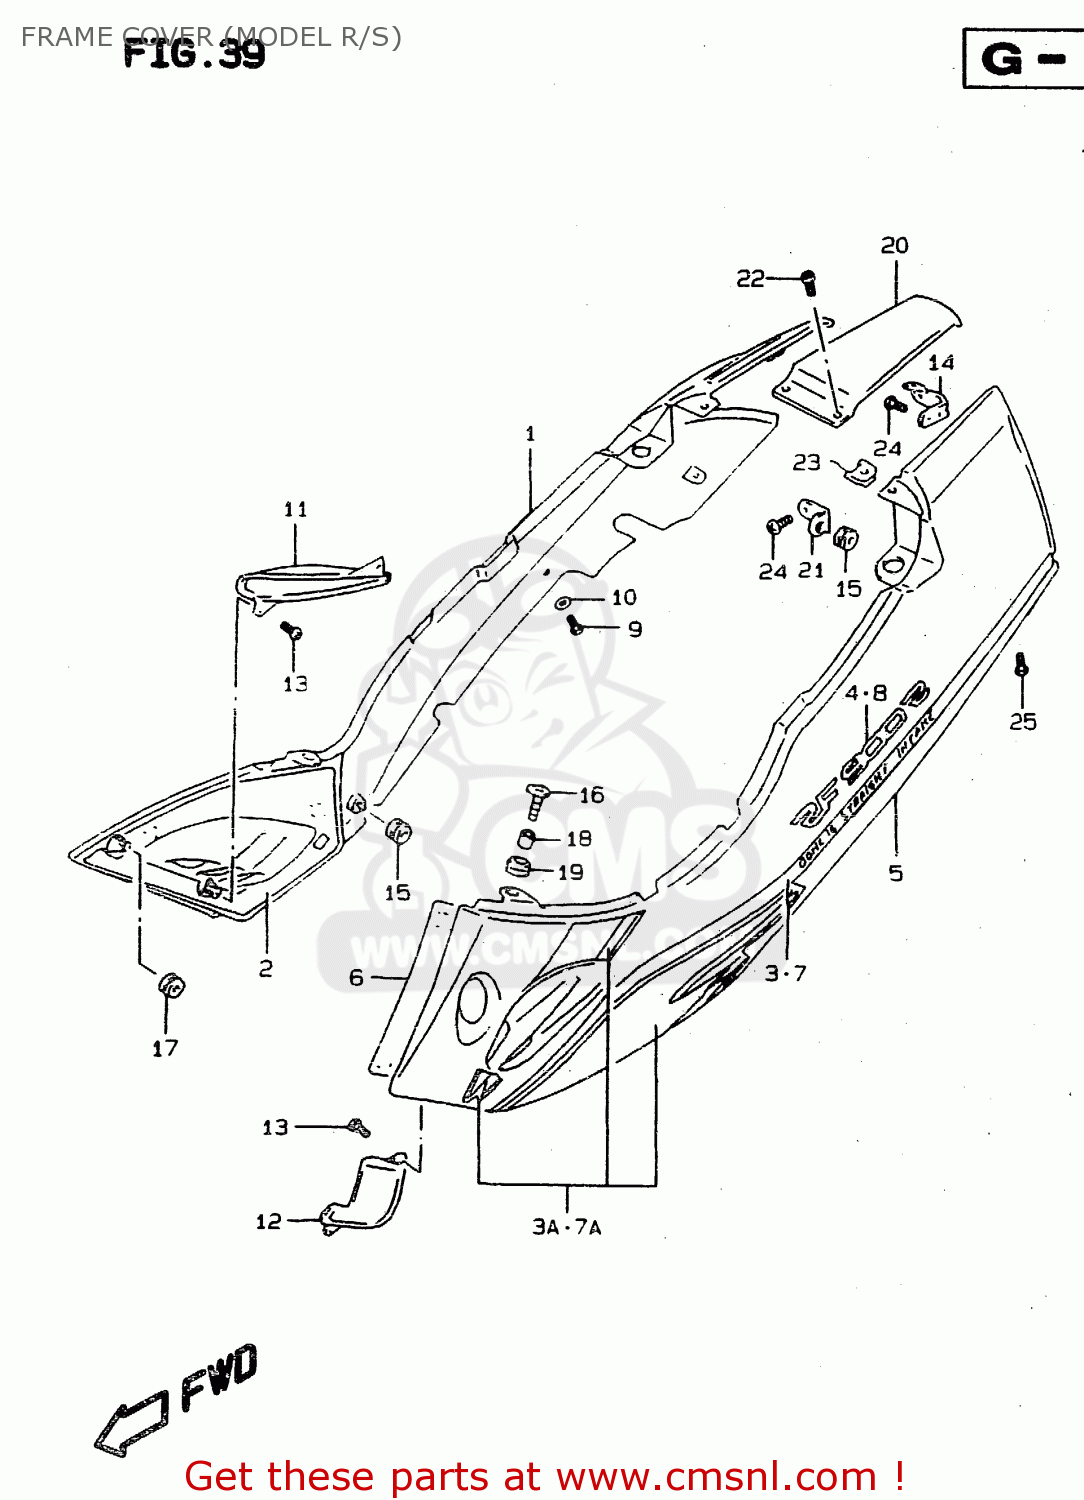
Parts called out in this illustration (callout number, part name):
1	COVER ASSY,FRAME,R(RED)
2	SHIELD,FRAME COVER HEAT
3	TAPE SET,FRAME COVER S
3A	TAPE SET,FRAME COVER,R
4	EMBLEM,FRAME COVER
5	COVER ASSEMBLY,FRAME,LEFT
6	SHIELD,FRAME COVER HEAT,L
7	TAPE SET,FRAME COVER S
7A	TAPE SET,FRAME COVER,LEFT
8	EMBLEM,FRAME COVER
9	SCREW 5X12
10	WASHER(5.2X14X1.5)
11	COVER,INNER,RIGHT
12	COVER,INNER,L
13	SCREW
14	BRACKET,FRAME COVER,R
15	CUSHION
16	SCREW
17	CUSHION,FRAME COVER FR
18	SPACER
19	CUSHION
20	COVER,FRAME CTR
21	BRACKET,RR COMBINATION LAMP
22	SCREW 5X12
23	NUT
24	SCREW
25	SCREW
